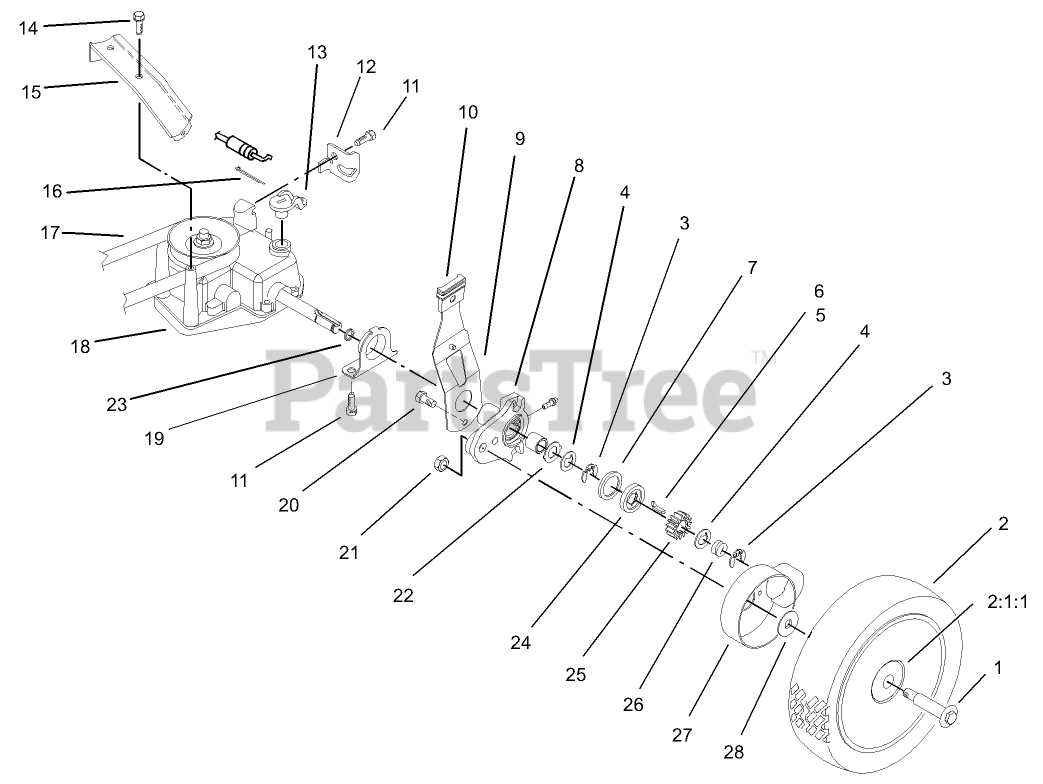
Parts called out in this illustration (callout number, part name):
1	BOLT-SHOULDER
2	WHEEL AND GEAR ASM
2:1	Wheel ASM
2:1:1	BUSHING
3	RING-RETAINING,CLIP
4	WASHER-THRUST, KEYED
5	KEY-ROCKING, LH
6	KEY-ROCKING, RH
7	RING-FRICTION
8	PIVOT ARM ASM
9	SPRING ARM ASM
10	KNOB-ARM
11	SCREW-HWHTF
12	RETAINER-CABLE
13	LEVER-SHIFT
14	SCREW-HWHTF
15	BRACKET-GUIDE, BELT
16	PIN-COTTER
17	V-BELT
18	GEARCASE ASM
19	CAP-END
20	SCREW-HWH
21	LOCKNUT
22	WASHER-ARM, PIVOT
23	O-RING
24	WASHER-CLUTCH
25	GEAR-PINION
26	SPRING-COMPRESSION
27	COVER-WHEEL
28	SPACER-COVER, WHEEL
